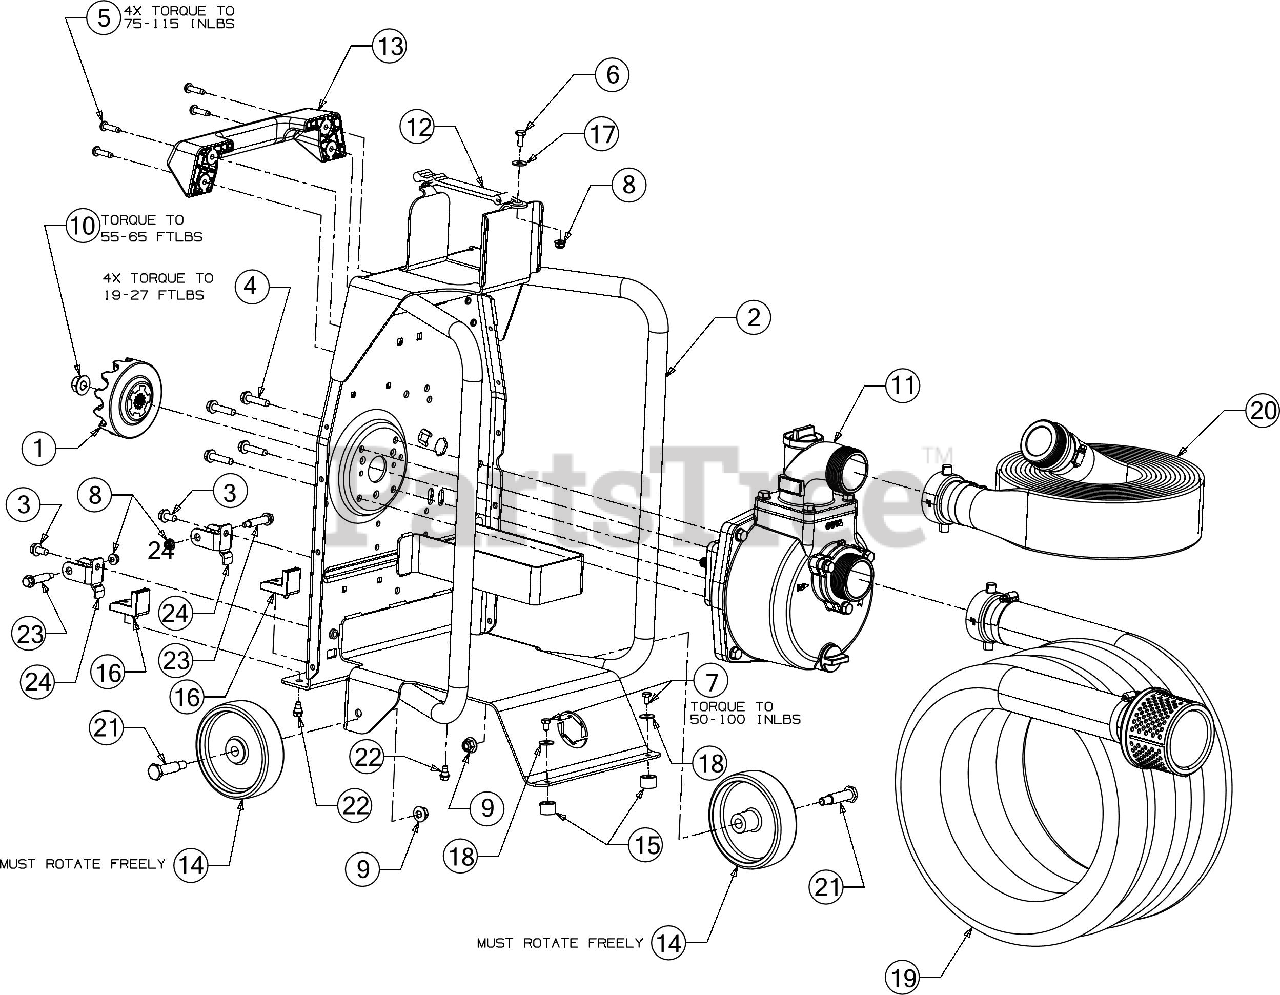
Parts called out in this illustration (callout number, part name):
1	DOG CLUTCH ASSEMBLY
2	WATER PUMP FRAME ASSEMBLY
3	SCREW 5/16-18 x .750
4	HEX SCREW WASHER 5/16-18 x 1.5
5	SCREW 1/4-20 x 1.0
6	SCREW 1/4-20 x .620 GR5
7	SCREW M6-1.0X10MM GR8.8
8	FLANGE LOCK NUT
11	WATER PUMP ASSEMBLY
12	RETAINER STRAP ASSEMBLY
14	PLASTIC WHEEL 5X1.38
16	BUMPER PAD
17	FLAT WASHER .28 ID x .74 OD x .063
18	SPRING WASHER BELL
19	SUCTION HOSE
20	DISCHARGE HOSE
21	SHOULDER SCREW
22	SHOULDER SCREW 1/4-20 x .50
23	SHOULDER SCREW
24	SUPPORT BRACKET
